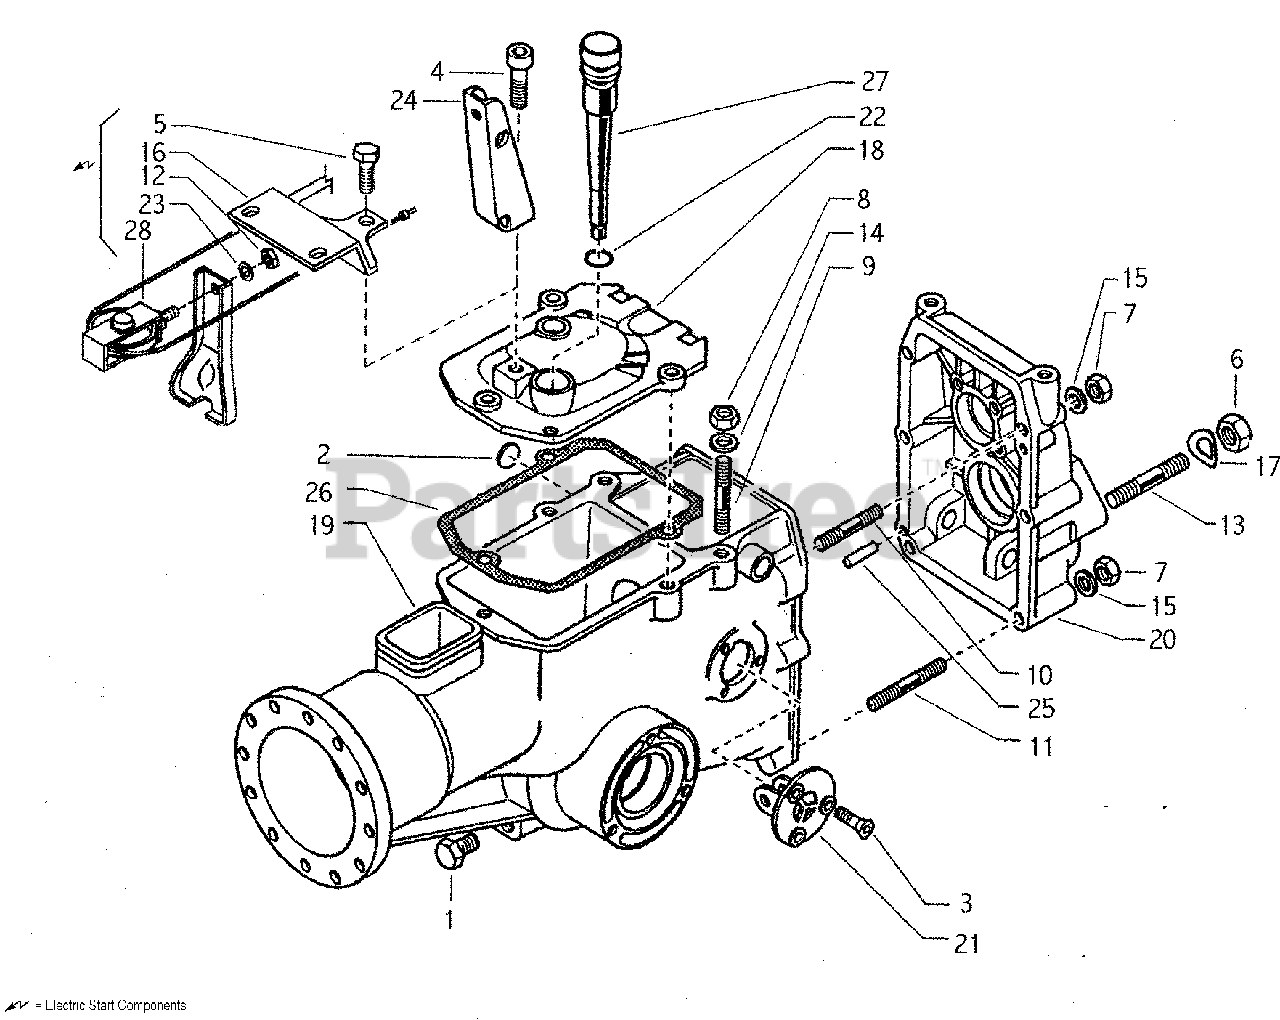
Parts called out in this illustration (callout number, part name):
3	SCREW, COUNTER SUNK, M6X16
4	SCREW M10X25
6	NUT, M12X1.25
7	NUT, SELF LOCKING M8
9	STUDM8X38X14X20
10	STUDM8X58X16X16
13	STUDM12X1.25X12X64
14	SUPER WASHER 8
15	WASHER, LOCK 8.4
17	WASHER, LOCK, M13
18	GEARBOX COVER
19	GEAR BOX CASE
21	REVERSER GEAR COVER
24	CLUTCH BRACKET
25	PARALLEL PIN
26	GASKET, COVER
27	CAP WITH DIP STICK
28	PULLEY ASSEMBLY
